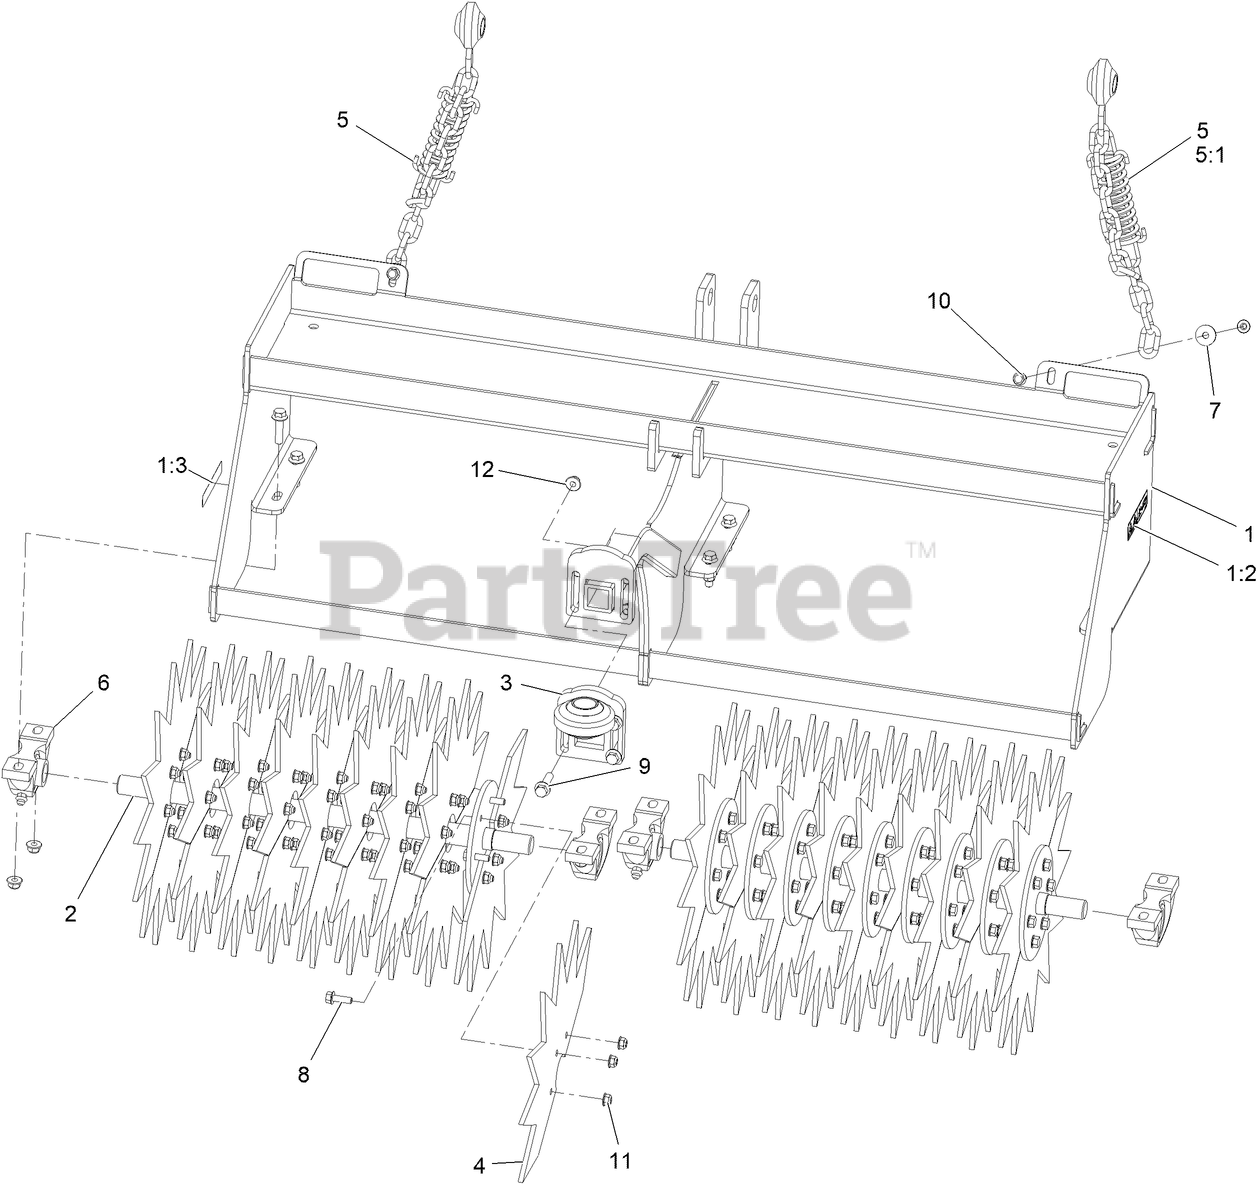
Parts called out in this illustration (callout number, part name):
1	Spiker Frame ASM W/Decals
1:2	DECAL-WARNING, TINES
1:3	DECAL-WARNING
2	DISC-SPYKER HEAD
3	MOUNT-SWIVEL BRG,AER HEAD
4	STAR, SPIKER HEAD
5	SWIVEL-CHAIN ASM
5:1	Z-PLUG DRAWBAR SPRING
6	PILLOW BLOCK BEARING
7	WASHER-FLAT
8	SCREW-HHF
9	SCREW-HHF
10	SCREW-HH
11	NUT-HF, NI
12	NUT-HF, NI
